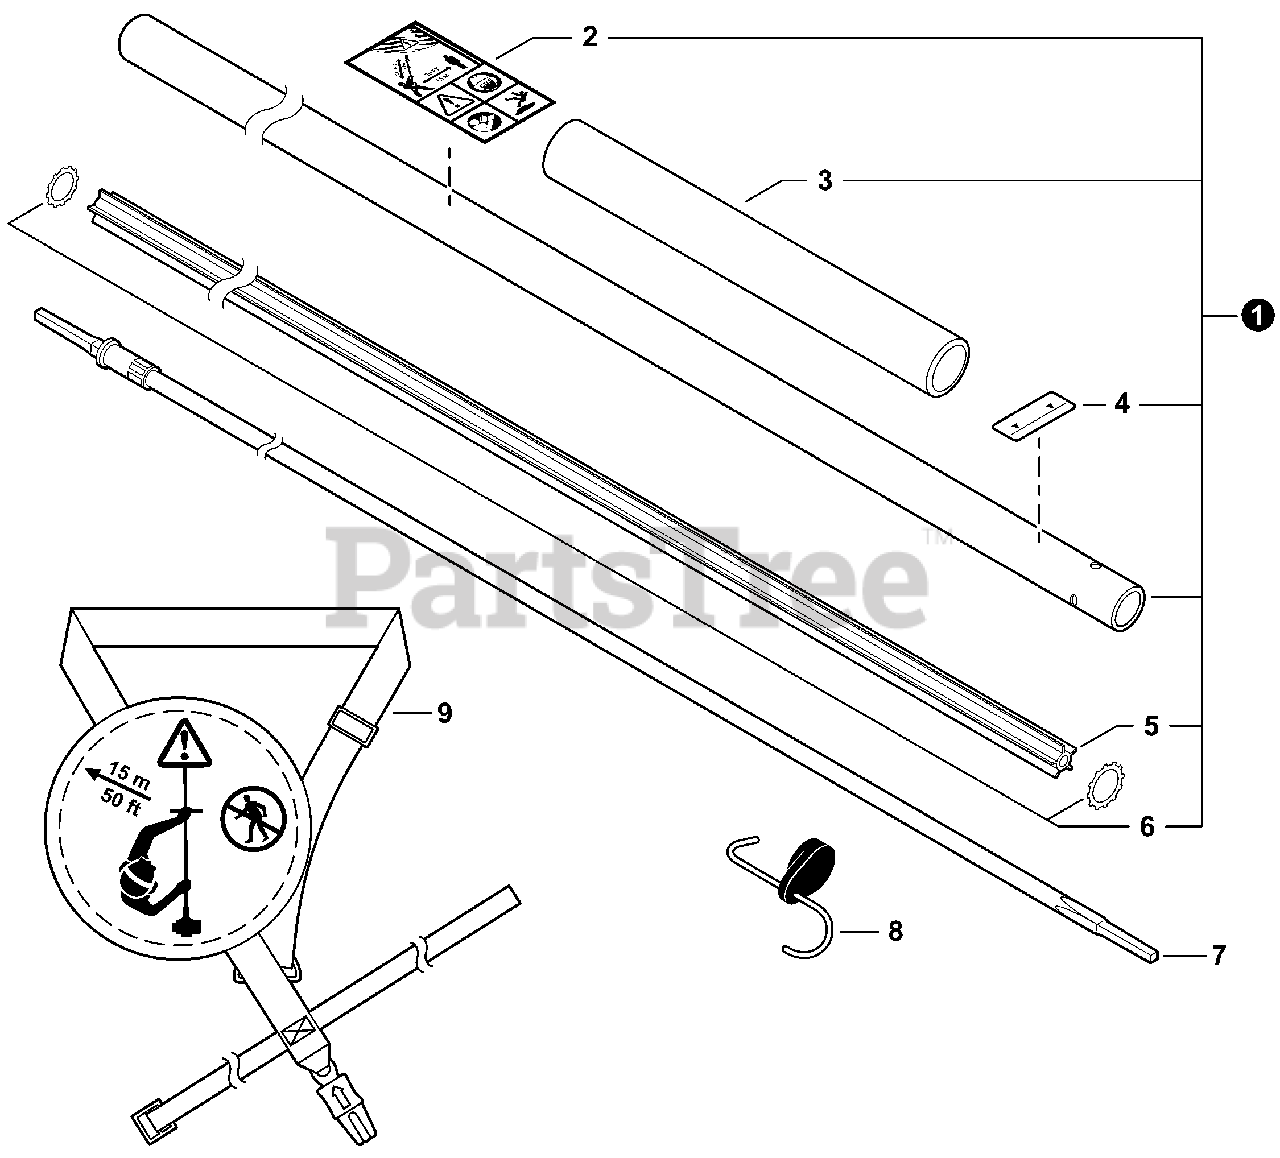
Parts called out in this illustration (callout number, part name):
1	MAIN PIPE ASSY
2	LABEL, CAUTION
3	GRIP, HANDLE
4	LABEL - ALIGNMENT
5	LINER - FLEXIBLE
7	DRIVESHAFT - FLEXIBLE
8	HANGER, ATTACHMENT
9	HARNESS, SHOULDER
